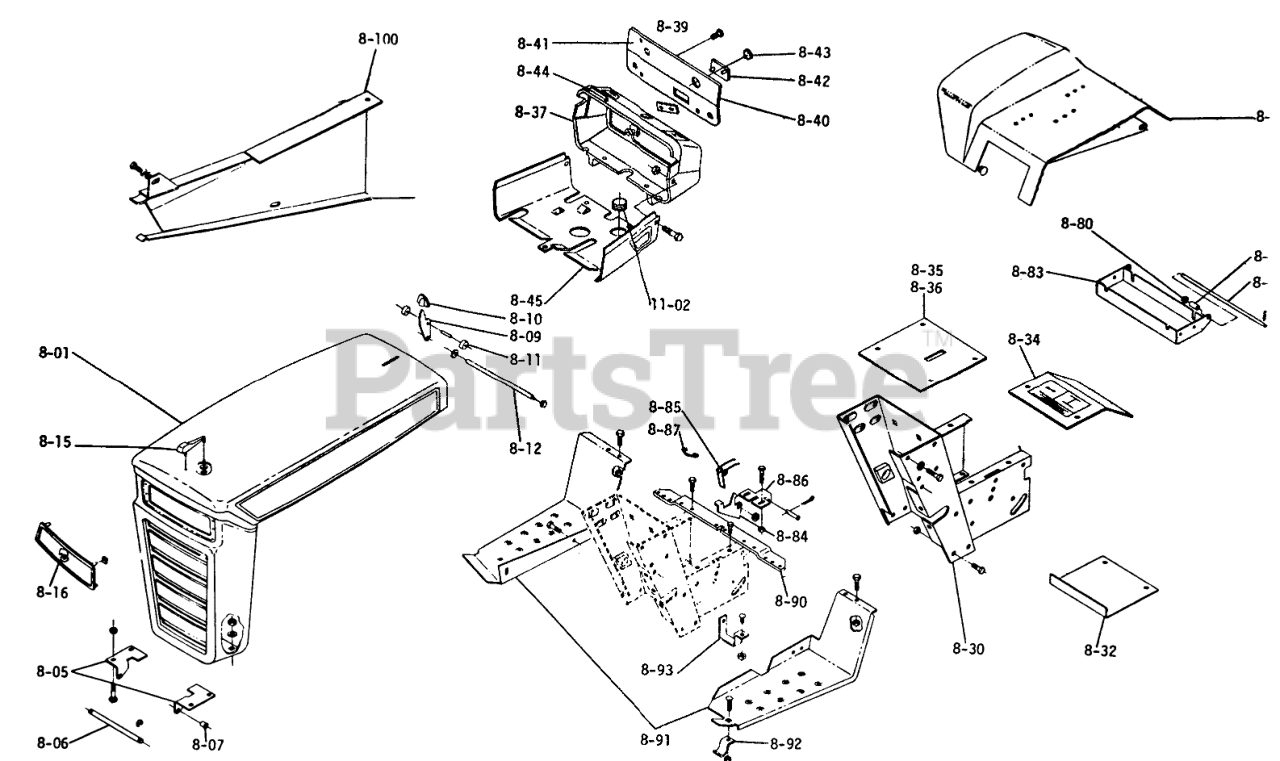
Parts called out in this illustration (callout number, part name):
8-05	Bolt Hex 5/16-18 x 3/4
8-05	Nut-Nylok
8-07	NYLINER BUSHING
8-09	LEVER HOOD LATCH
8-09	SPIROL PIN
8-10	KNOB
8-12	Nut-Hi Crown
8-15	Hood Ornament
8-16	Speed Nut, push on
8-20	Tape
8-30	Assy.-Hoodstand
8-30	Bolt 3/8-16 x 1
8-30	Washer
8-32	Cover-Dust
8-34	Plate-Cover
8-34	Bolt, 1/4-20 Whizlock
8-36	Plate-Back up
8-37	Bolt Hex 5/16-18
8-37	Lockwasher
8-39	Panel-Control
8-41	Plate-Support
8-41	*Screw #10-16 x 3/4
8-43	*Plug Button-Lighter
8-45	Bolt 1/4-20 x 5/8 Whizlock
8-45	Nut-Nylok
8-71	GROMMET
8-81	Spacer
8-82	Rod-Sat Pivot
8-82	Hairpin
8-83	Tool Box
8-83	Bolt Hex 5/16-18 x 3/4
8-83	Nut-Nylok
8-83	Bolt 3/8-16 x 1
8-85	Spring
8-85	NYLINER BUSHING
8-85	Hairpin
8-86	Bolt-Hex 1/4-20
8-86	Nut-Nylok
8-87	Stop-Fender Latch
8-90	Bolt, 5/16-18 x 1/2
8-90	Bolt, 5/16-18 X 7/8
8-90	Nut-Nylok
8-91	Footrest R.H.
8-91	Bolt 5/16-18 x
8-91	Nut 5/16-18
8-91	Bolt, 5/16-18 x 1/2
8-92	BRACKET
8-92	Bolt-Carriage 5/16-18
8-92	Nut 5/16-18
8-100	Assy.-Belt Guard
8-100	Bolt, 5/16-18 x 1/2
8-100	Bolt 3/8-16 x 3/4
8-100	Lockwasher
8-100	Washer
